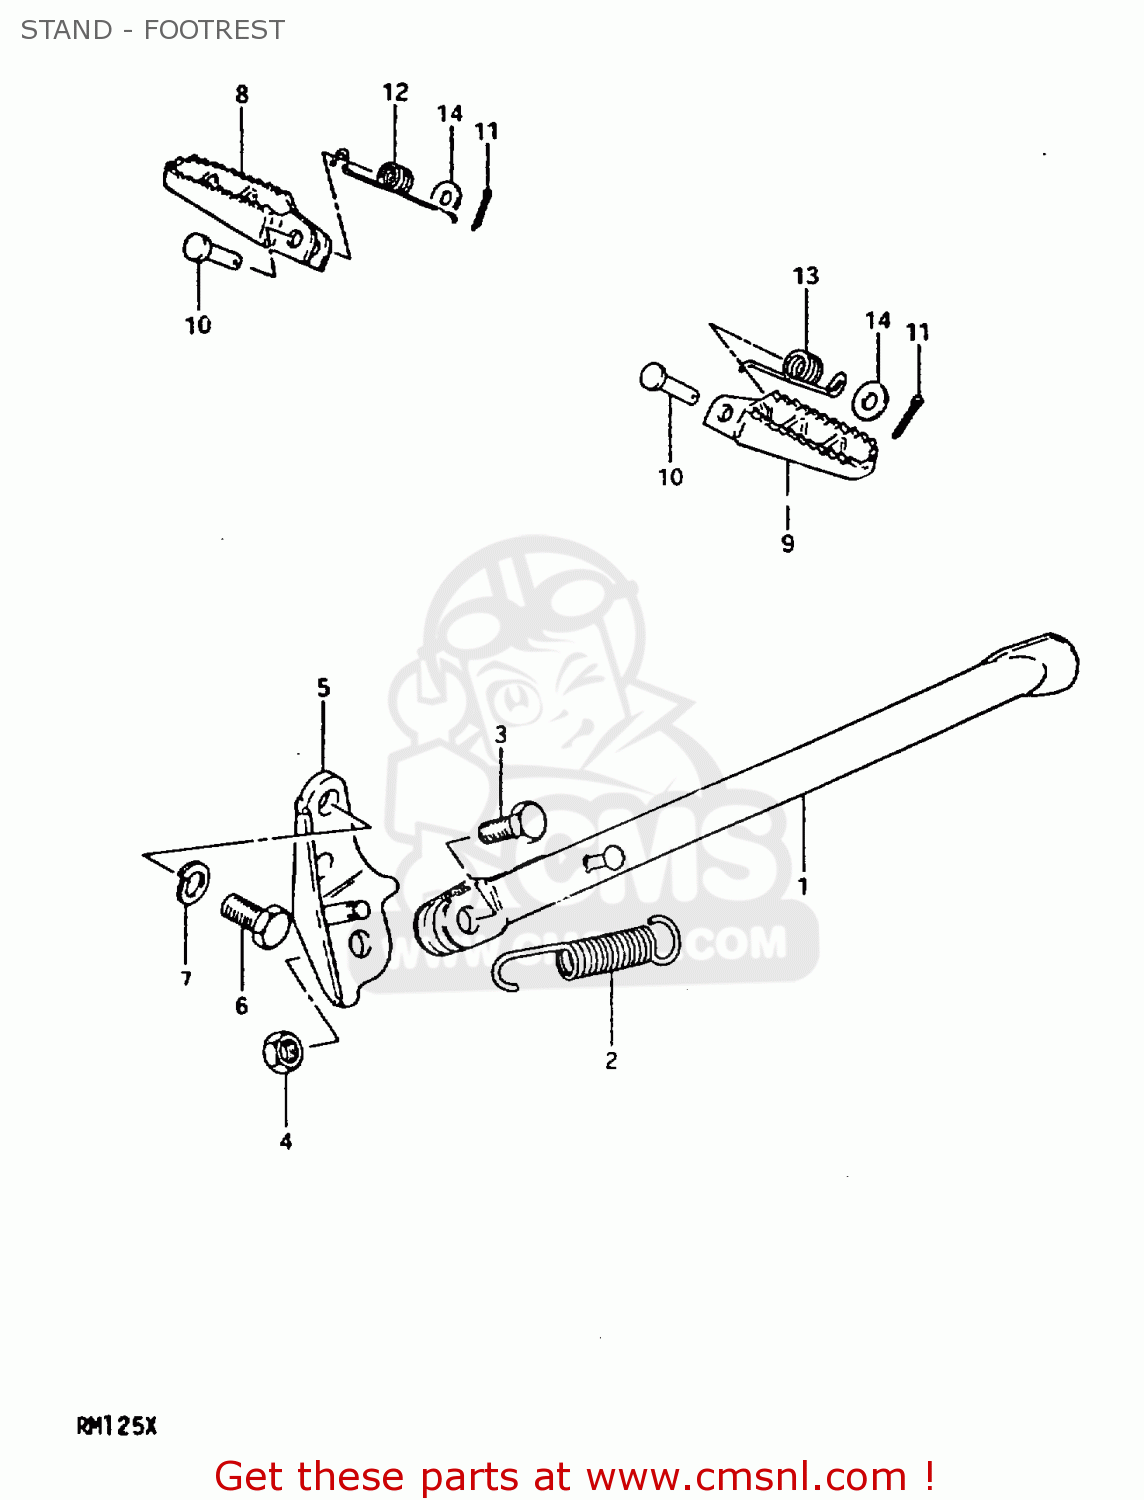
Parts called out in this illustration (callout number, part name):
1	STAND,SIDE
2	SPRING
3	BOLT(10X30)
4	NUT
5	BRACKET,SIDE STAND
6	BOLT(10X19)
7	LOCK WASHER
8	RUBBER,FRONT FOOTREST
9	FOOTREST
10	PIN
11	PIN 20X20
12	SPRING
13	SPRING
14	WASHER
